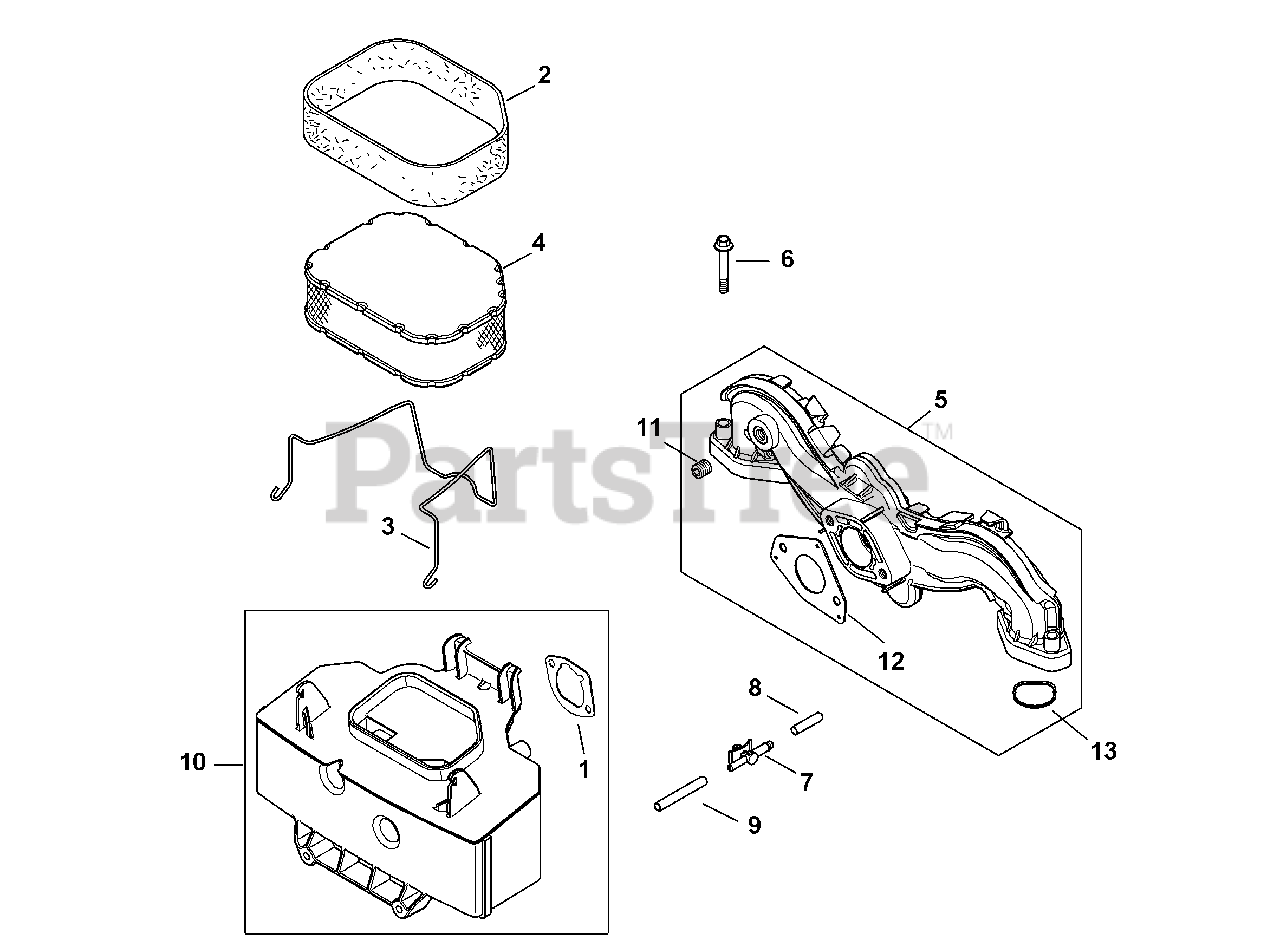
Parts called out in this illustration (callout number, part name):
1	Air Cleaner Base Gasket
2	Pre-Cleaner Element
3	Air Cleaner Element Latch
4	Air Filter & Pre-Cleaner Elements
5	Intake Manifold Kit
6	Flange Screw, M6 x 1.0 x 40
7	Evaporative Connector
8	Evaporative Mask
9	Evaporative Hose, 20"
10	Air Cleaner Base
11	Pipe Plug, 1/8
12	Carburetor Gasket
13	Intake Port O-Ring
